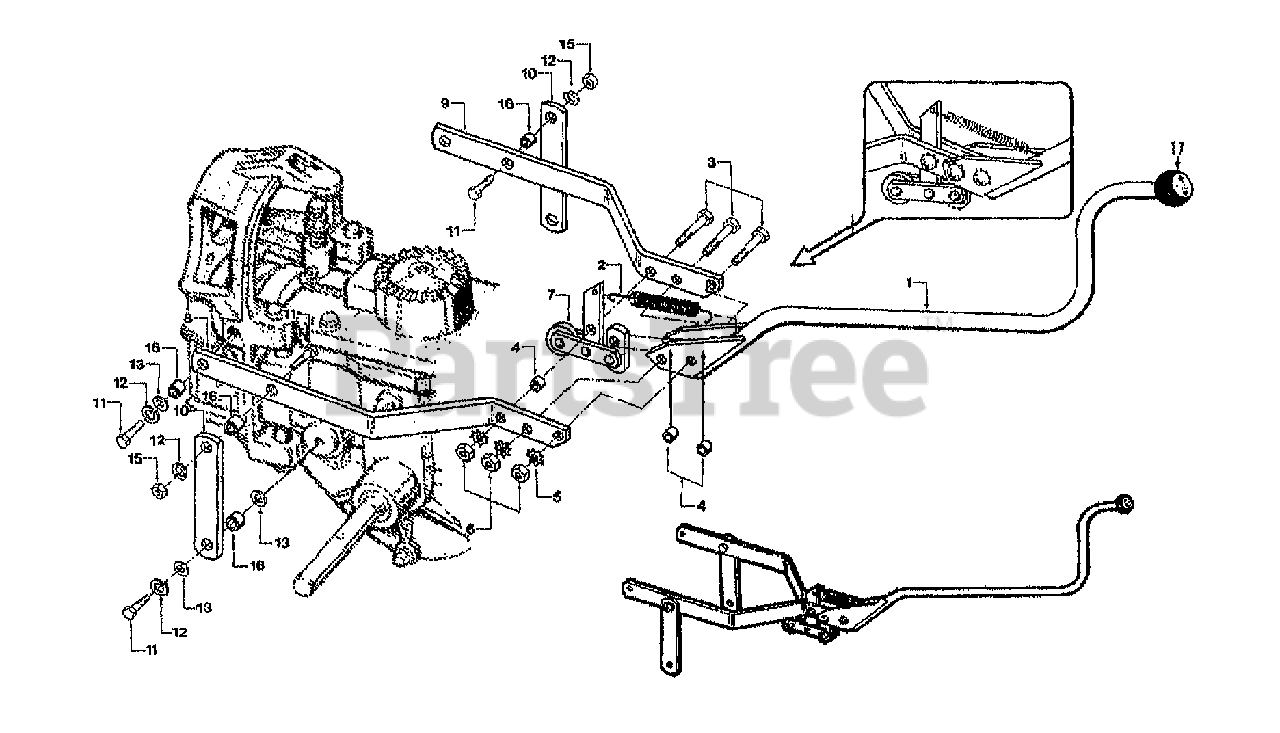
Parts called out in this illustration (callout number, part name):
1	ASSM-FOR/REV LEVER (INCL. KNOB W/DECAL)
2	SPRING-.436 X 3.25
3	SCR-HH 5/16-18X1.5 G5 ZP
4	BUSHING-.5X.316X.375 PM
5	WASHER-LK .312 EXT TOOTH
6	NUT-HEX 5/16-18 ZP
7	ASSM-ROLLER PAINT
8	YOKE-LH RED
9	YOKE-RH RED
10	YOKE-RED 2164
11	SCR-HH 3/8-16X1.0 G5 ZP
12	WASHER-LK .375 @ DEPL
13	WASHER-FLAT 3/8 SAE
14	THIS REF. NO. NOT USED
15	NUT-HEX 3/8-16 ZP
16	BUSHING-.5X.375X.3 (.300")
17	KNOB - NOT AVAIL. SEPARATELY. SEE REF. NO. 1
